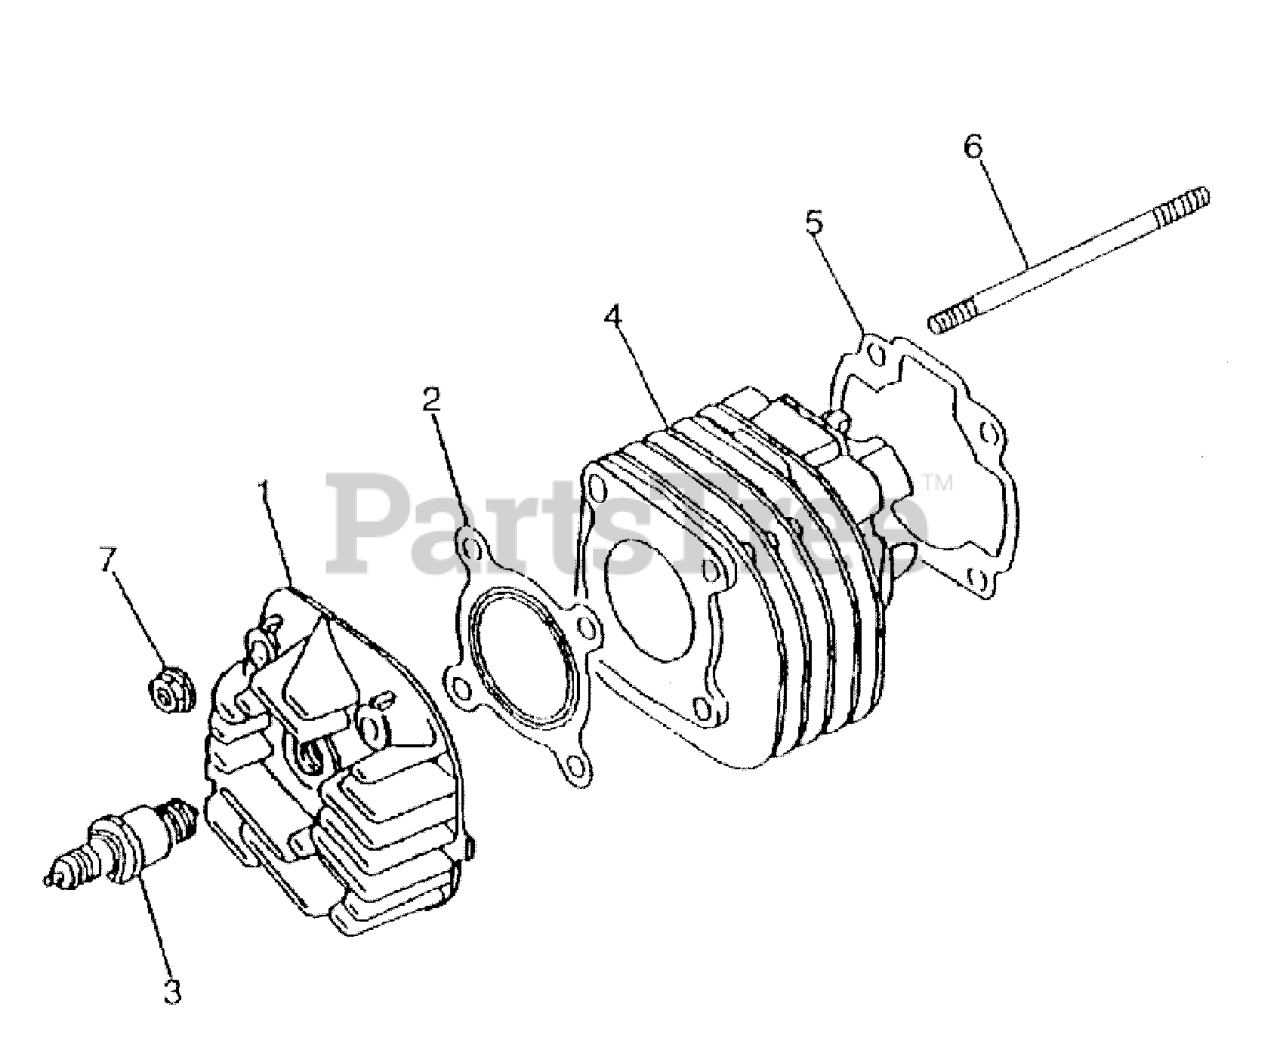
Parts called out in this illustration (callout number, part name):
1	HEAD, CYLINDER
2	GASKET, CYLINDER HEAD
3	SPARK PLUG
4	CYLINDER
5	GASKET, CYLINDER
6	STUD BOLT
